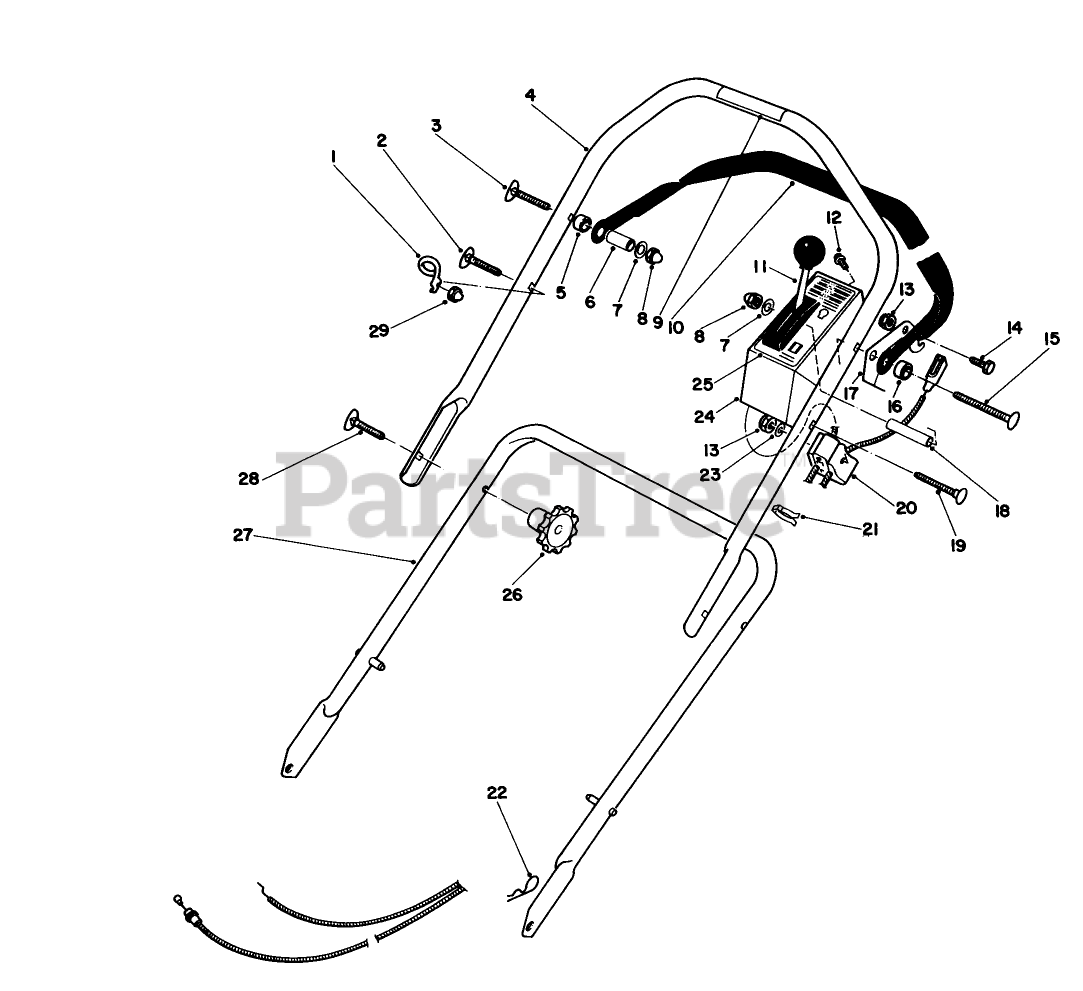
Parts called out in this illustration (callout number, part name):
2	HANDLE SCREW
5	SPACER-NYLON
7	WASHER-PLAIN
8	NUT-ACORN
12	SCREW-HWHTF
13	NUT-LOCK, NI
14	SCREW-HH
19	SCREW-HANDLE
20	SUPPORT-CABLE
21	BOWDEN CLIP
22	PIN-COTTER, HAIR
23	WASHER-FLAT
29	NUT-CAP
